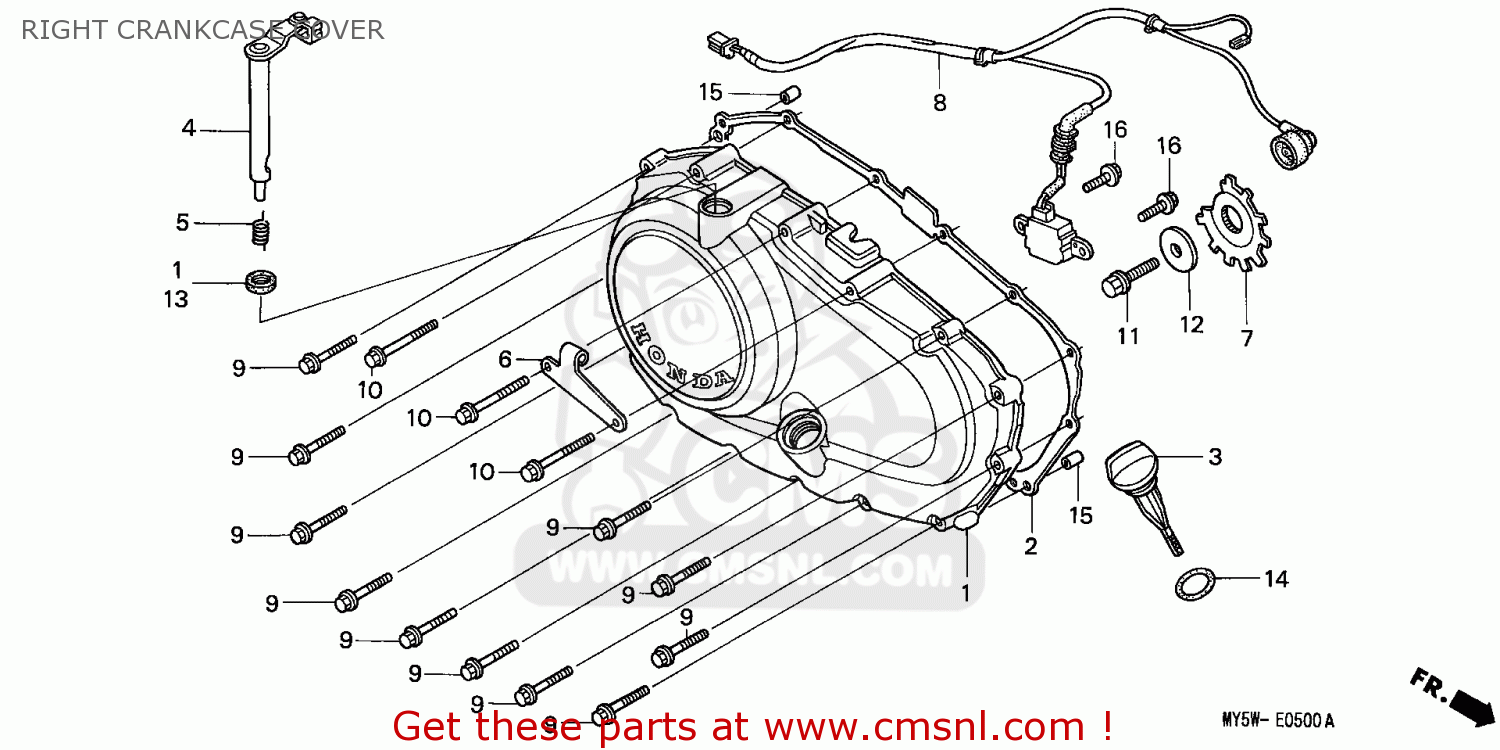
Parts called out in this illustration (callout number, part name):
1	COVER COMP,R
2	GASKET,R COVER (NAS)
3	GAUDE,OIL LEVEL
4	LEVER COMP,CLUTCH
5	SPG,CLUTCH LEVER
6	RECEIVER,CLUTCH C
7	ROTOR,PULSE
8	PULSE GEN ASSY
9	BOLT,FLANGE,NSHF,
10	BOLT,FLANGE,NSHF,
11	BOLT,FLANGE,10MM
12	WASHER,10X36X4.5
13	OIL SEAL 12X18X5
14	ORING 183
16	BOLT,FLANGE 6X14
